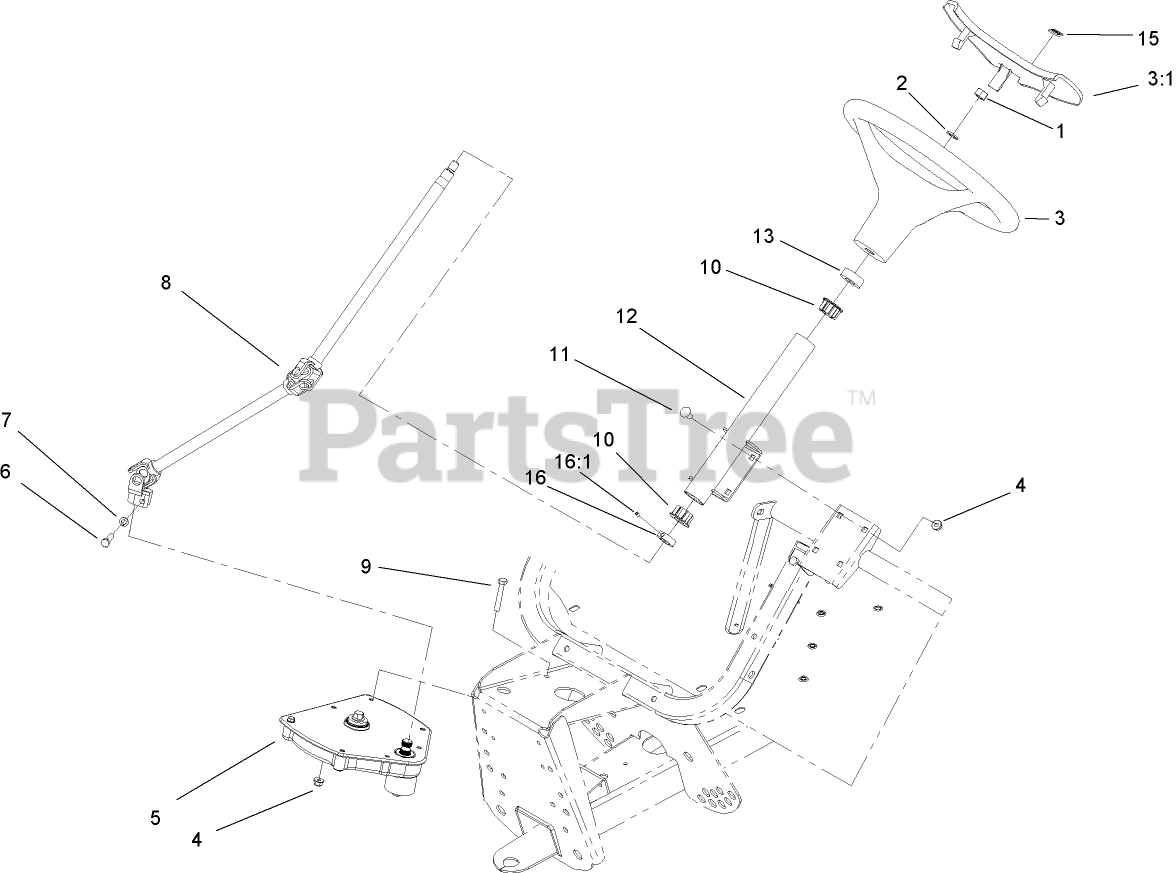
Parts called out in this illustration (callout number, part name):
1	NUT-HEX
2	WASHER-LOCK
3	WHEEL-STEERING
3:1	COVER-WHEEL, STEERING
4	NUT-HF, NI
5	STEERING GEARBOX ASM
7	WASHER-LOCK
8	SHAFT-STEERING
9	SCREW-HH
10	BUSHING-STEERING, UPPER
11	BOLT-CARR
12	COLUMN-STEERING
13	COVER-DUST
15	DECAL
16	COLLAR
16:1	SCREW-HSH
